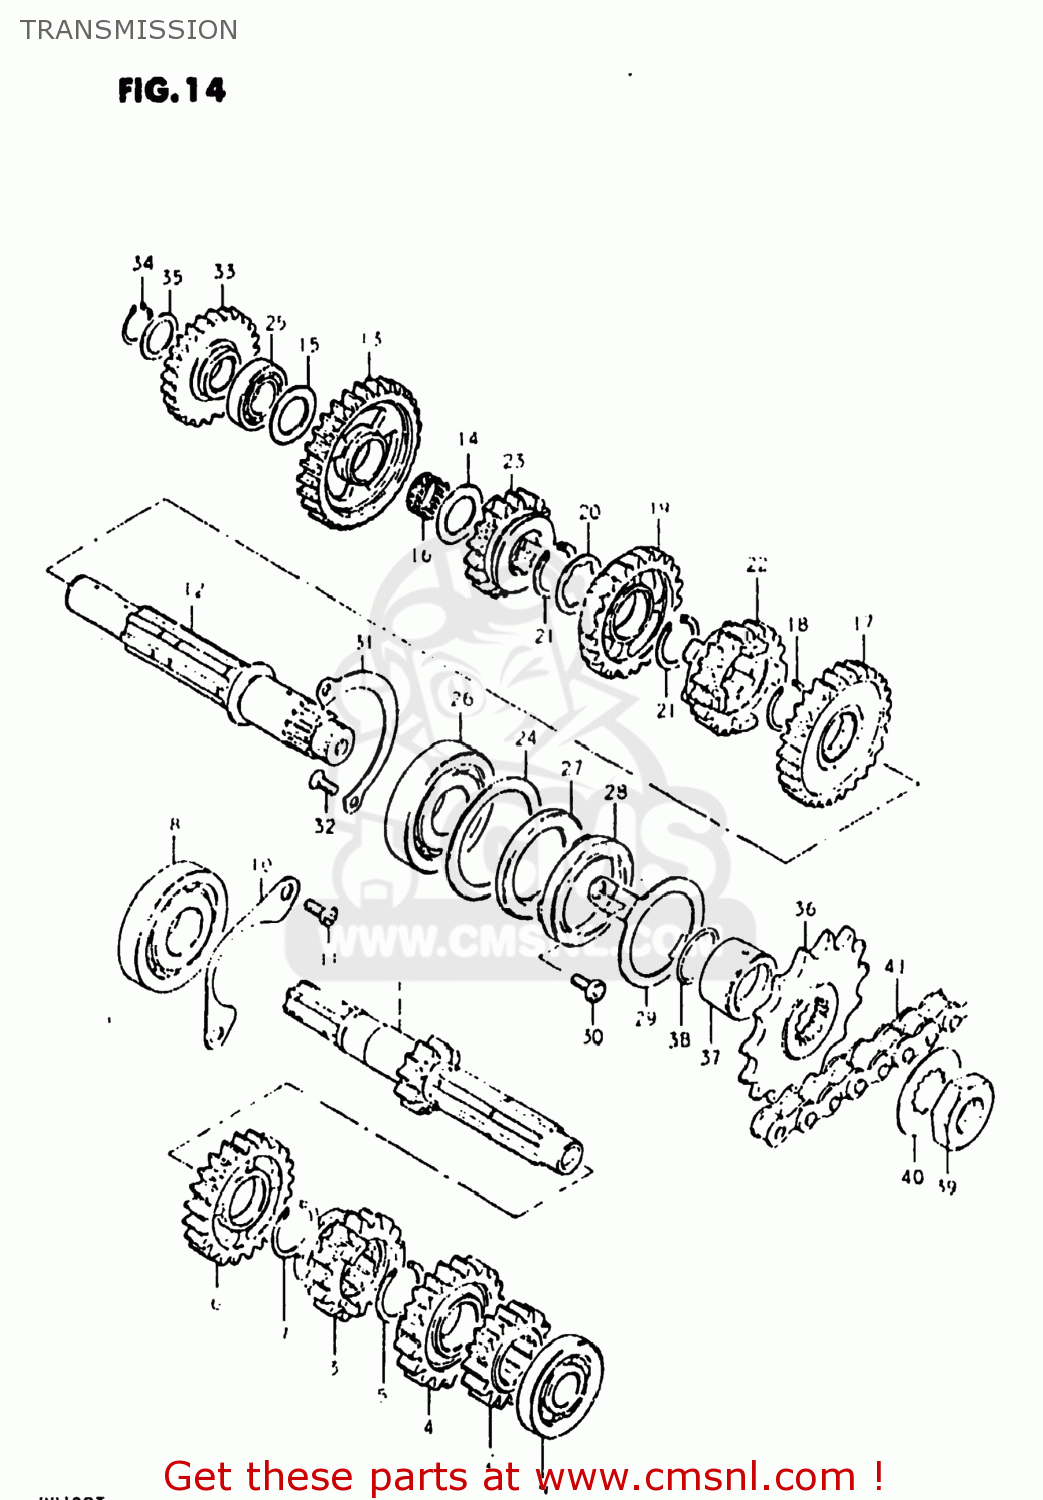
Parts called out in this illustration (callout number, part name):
1	SHAFT,COUNTER
2	GEAR,SECOND DRIVE
3	GEAR,THIRD DRIVE
4	GEAR,FOURTH DRIVE
5	CIRCLIP
6	GEAR,FIFTH DRIVE
7	CIRCLIP
8	BEARING
9	BEARING
10	PLATE,COUNTERSHAFT BEARING
11	SCREW 6X12
12	SHAFT,DRIVE
13	GEAR,FIRST DRIVEN
14	WASHER
15	WASHER
16	BEARING(17X21X9.8)
17	GEAR,SECOND DRIVEN
18	CIRCLIP
19	GEAR,THIRD DRIVEN
20	WASHER,LOCK
21	CIRCLIP
22	GEAR,FOURTH DRIVEN
23	GEAR,FIFTH DRIVEN
24	WASHER
25	BEARING(17X36X12)
26	BEARING(22X56X16)
27	OIL SEAL (30X47X5)
28	SEAL,OIL(30X47X7)
29	PLATE,DRIVESHAFT OIL
30	SCREW 6X12
31	RETAINER,DRIVE SHAFT BEARING
32	SCREW
33	GEAR,KICK STARTER IDLER(NT:25)
34	CIRCLIP
35	WASHER
36	SPROCKET,ENGINE(NT:16)
37	SPACER,ENGINE SPROCKET
38	O RING(D:2.5,ID:21)
39	NUT
40	WASHER,LOCK
41	CHAIN ASSEMBLY,DRIVE
